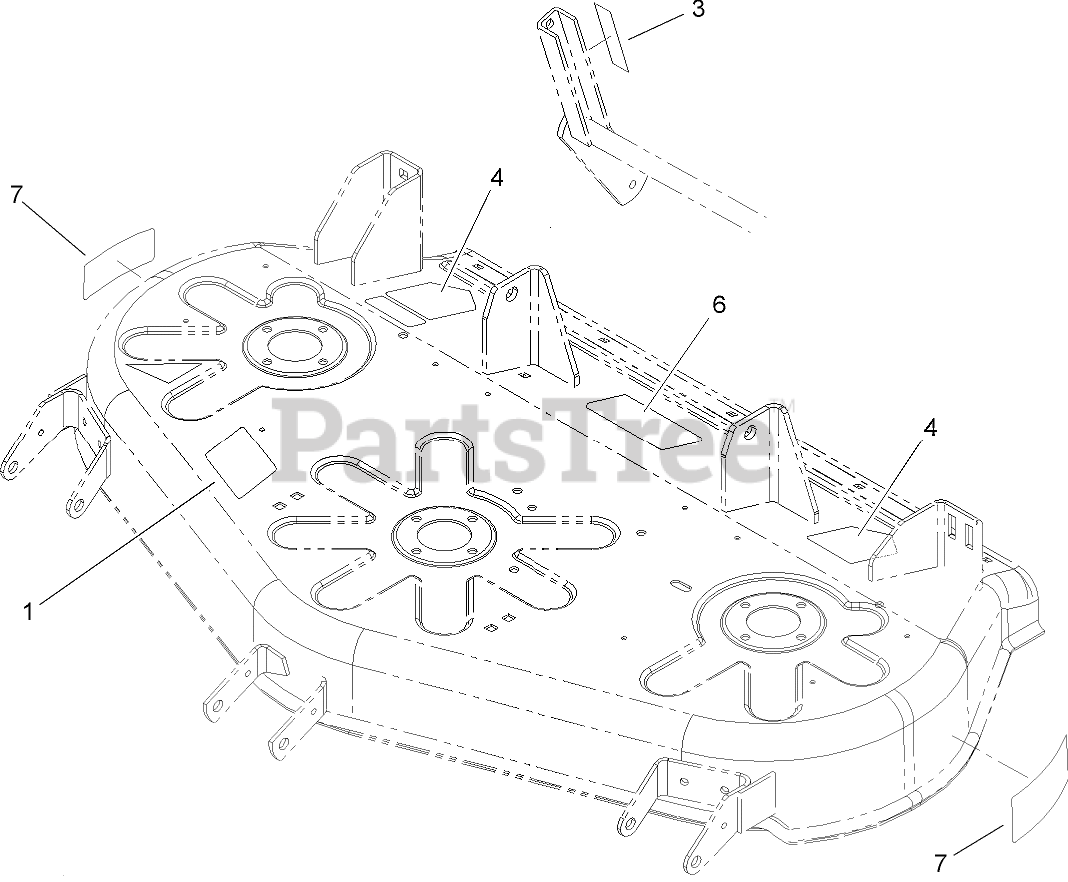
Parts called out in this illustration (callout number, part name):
1	DECAL-BELT ROUTING, PTO
3	DECAL-HOC
4	DECAL-DANGER
6	DECAL-BELT ROUTING
7	DECAL-DANGER
